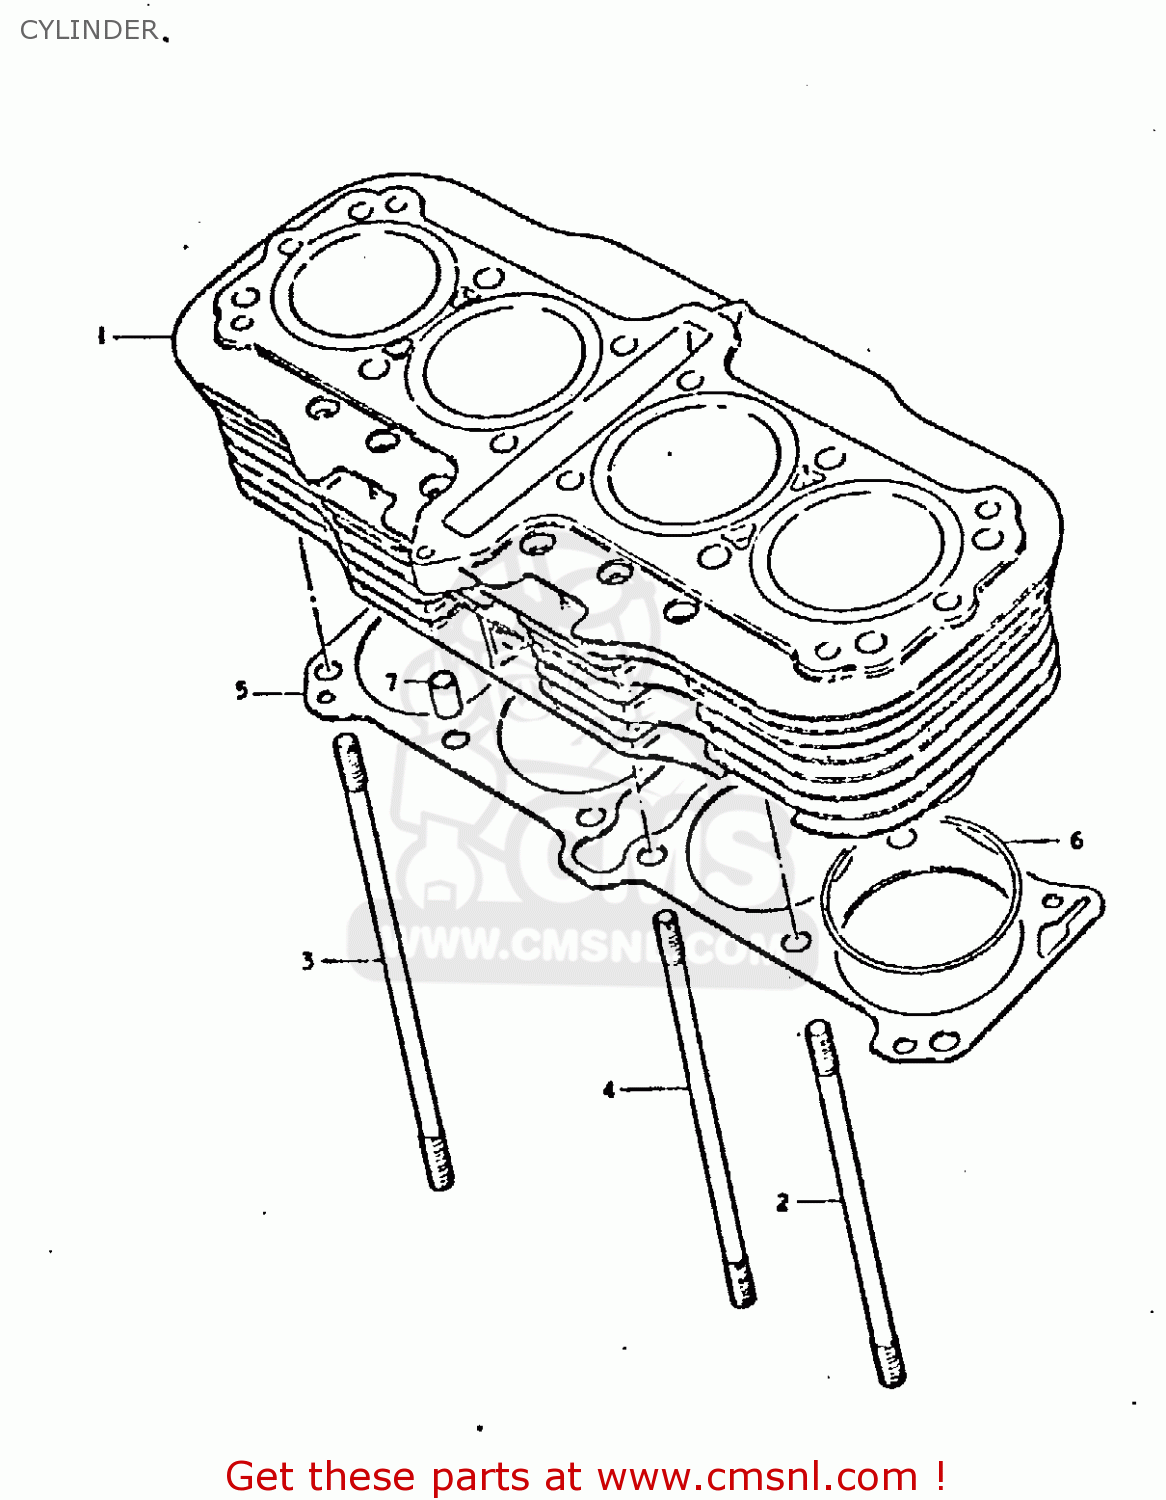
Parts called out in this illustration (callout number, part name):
1	CYLINDER
2	STUD
3	STUD
4	STUD
5	GASKET,CYLINDER (MCA)
6	O RING(D:2,ID:70)
7	PIN
